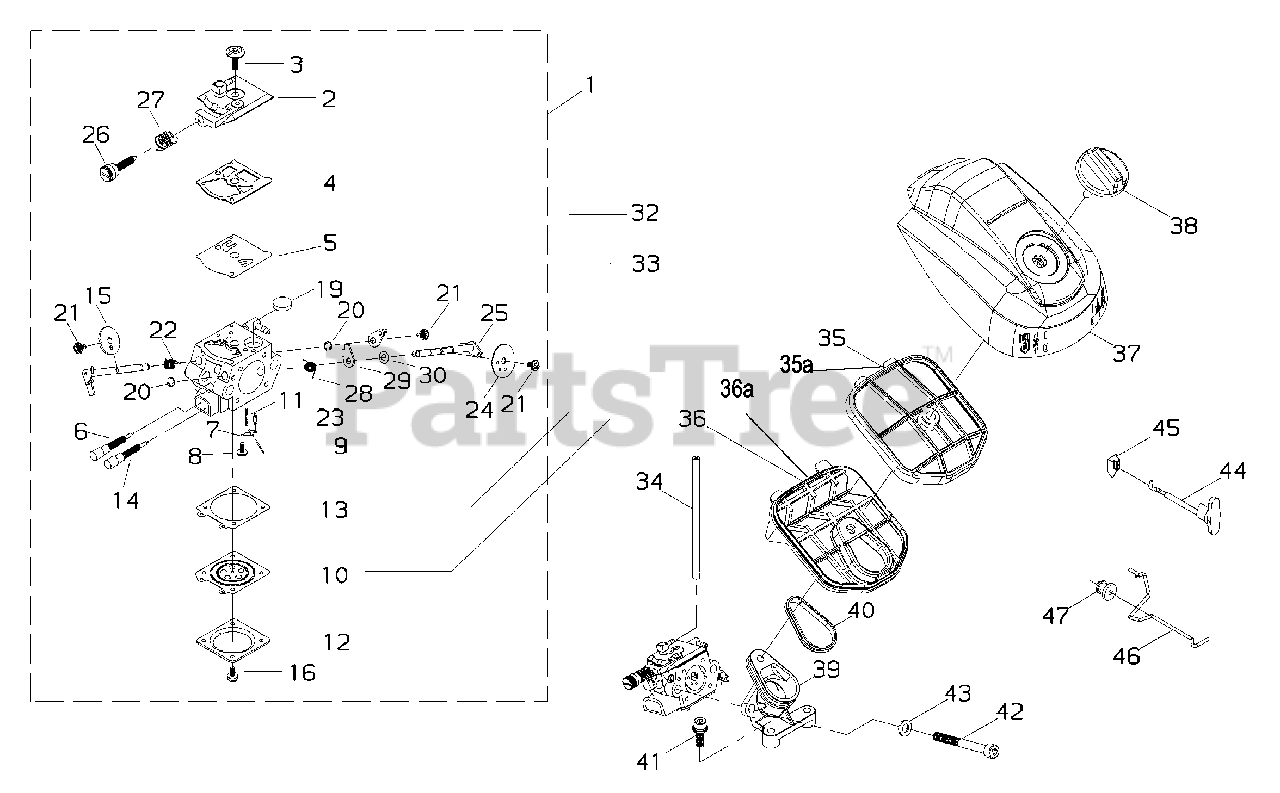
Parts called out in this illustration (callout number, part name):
1	CARBURETOR
2	PUMP COVER ASSY
3	SCREW, PUMP COVER
4	GASKET, PUMP
5	DIAPHRAGM, PUMP
6	NEEDLE - LOW SPEED
7	LEVER, METERING
8	SCREW, METERING LEVER PIN
9	PIN, METERING LEVER
10	DIAPHRAGM, METERING
11	SPRING, METERING LEVER
12	COVER, DIAPHRAGM
13	GASKET, METERING
14	NEEDLE - HIGH SPEED
15	VALVE, THROTTLE
16	SCREW
19	STRAINER
20	RING, RETAINING
21	SCREW
22	SPRING, THROTTLE RETURN
23	VALVE, INLET NEEDLE
24	VALVE, CHOKE
25	SHAFT, CHOKE
26	SCREW, IDLE ADJUST
27	SPRING
28	SPRING, CHOKE RETURN
30	WASHER
32	GASKET KIT
33	DIAPHRAGM KIT
34	PULSE TUBE
35	FILTER, AIR
36	CASE, AIR FILTER
37	COVER, AIR FILTER
38	THUMBSCREW
39	ADAPTER, AIR FILTER
40	GASKET
41	SCREW - 4X16
42	SCREW - 5X48
43	WASHER - 5
44	ROD, CHOKE
46	ROD, THROTTLE
47	GROMMET
